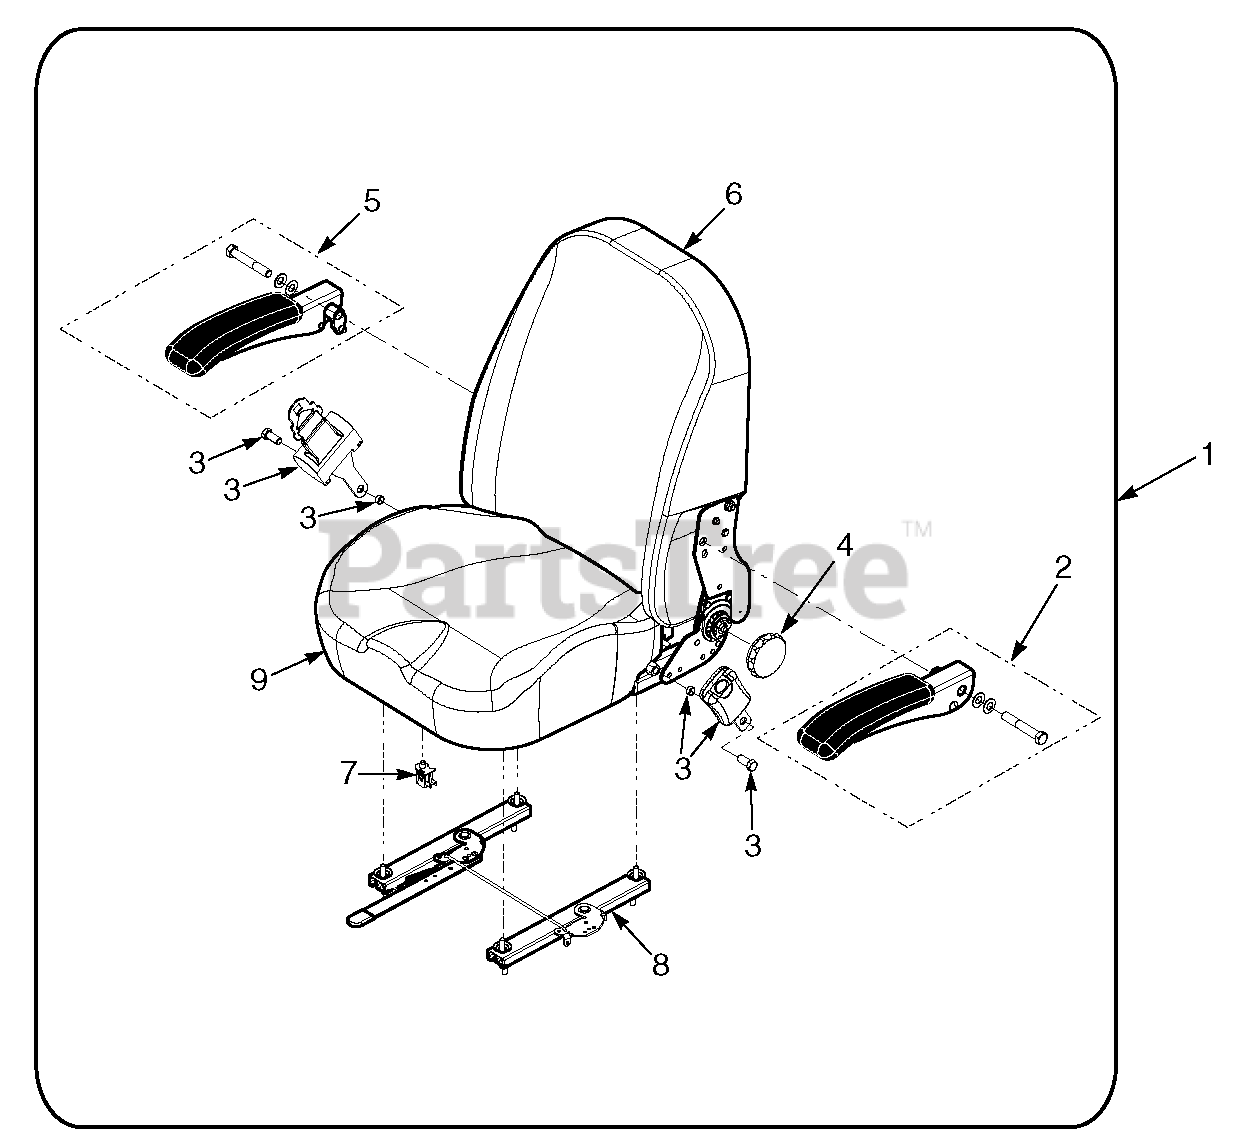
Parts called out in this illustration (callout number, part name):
1	Seat Assembly - SCZ
2	Armrest Kit, LH
3	Seat Belt Kit
4	Recliner Knob
5	Armrest Kit, RH
6	Back Cover
7	Seat Switch
8	Track Kit
9	Cushion Cover
